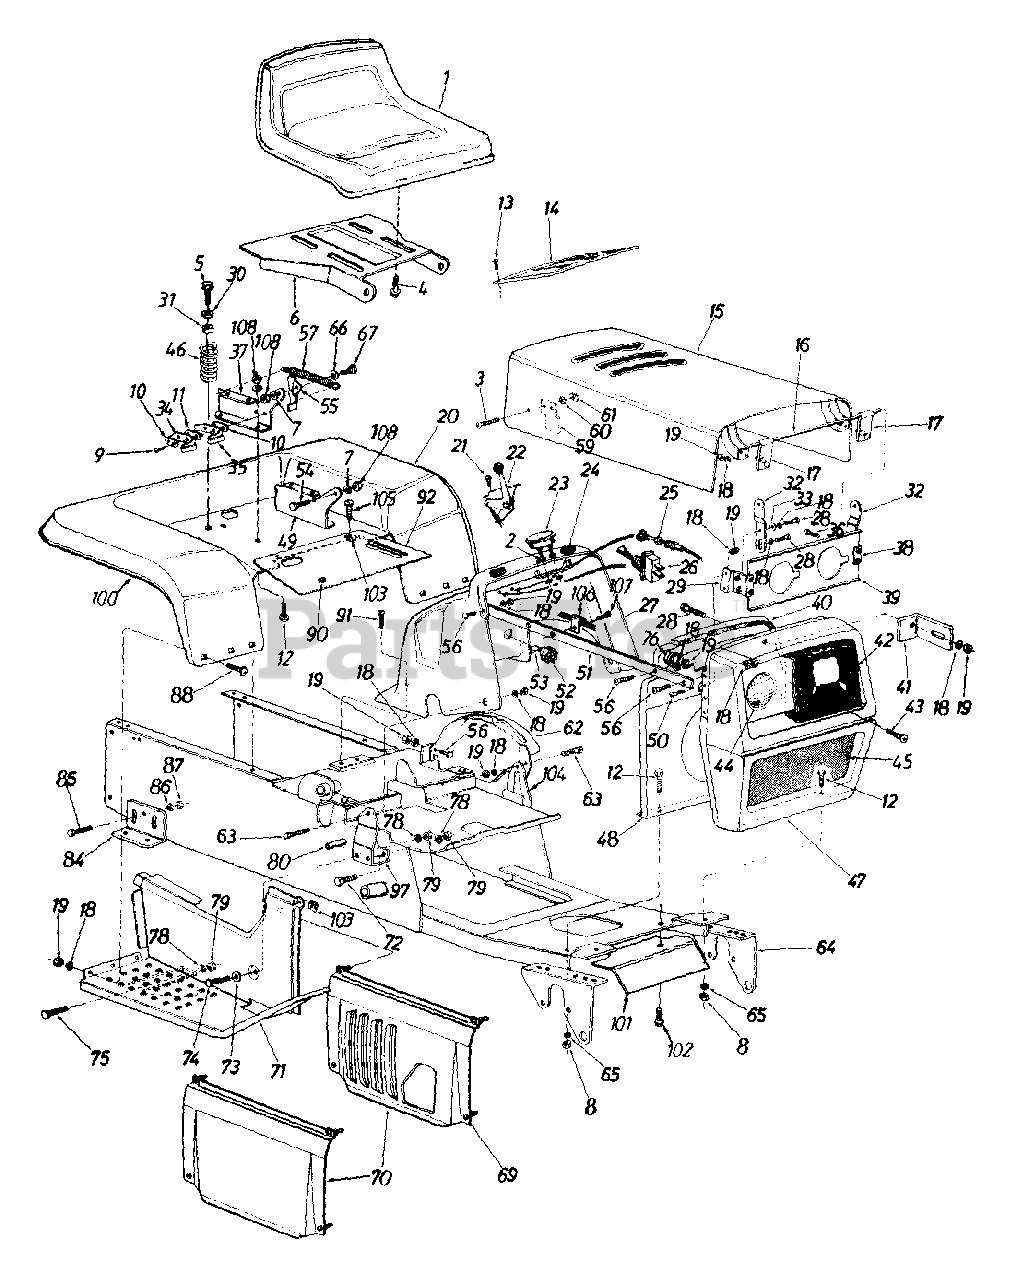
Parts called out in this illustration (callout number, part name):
1	Seat Ass'y.
2	L-Wash. .190" I.D.
3	Truss Hd. Mach. Scr. #10-24 x .38" Lg.
4	Hex Wash. Hd. Self-Tap Scr. 3/8-16 x .62" Lg. (Gr. 5)
5	Hex Wash. Hd. Tap Scr. 5/16-18 x .75" Lg.
7	L-Wash. 5/16" I.D.
8	Hex Nut 5/16-18 Thd.
9	Hex Wash. Hd. AB-Tap Scr. #8 x .5" Lg.
10	Insulator Plate
11	Insulator Boss Plate
12	Hex Bolt 5/16-18 x .75" Lg.
13	Self-Tap Oval Hd. Scr. 1/2" Lg.
14	Dash Panel Cover
17	Hood Hinge Ass'y.
18	L-Wash. 1/4" I.D.
19	Hex Nut 1/4-20 Thd.
22	Throttle Control
23	Ammeter
24	Rubber Bumper
25	Choke Control
26	Light Switch
27	Dash Panel
28	Hex Bolt 1/4-20 x .62" Lg."
29	Hood Support Brkt. Ass'y. - R.H.
30	Fl-Wash. .344" I.D. x .875"
31	Bushing
34	Safety Switch (Seat)
35	Safety Switch (Seat)
36	Hex Bolt 1/4-20 x .38" Lg.
37	Seat Pivot Support Brkt. - R.H.
38	Hood Support Brkt. Ass'y. - L.H.
41	Heat Shield Brkt.
42	Head Lamp Bezel
43	Truss Mach. Scr. #10-24 x .50" Lg.
44	Head Lamp
45	Grille Screen
46	Compression Spring 4.5" Lg.
50	Truss Mach. Scr. 1/4-20 x .75" Lg.
53	Ignition Key
54	Shld. Bolt .437" Dia. x .162"
55	Seat Lift Bracket
56	Hex Bolt 1/4-20 x .75" Lg.
57	Extension Spring 5.31" Lg.
59	Hood Spring
60	L-Wash. #10
61	Hex Nut #10-24 Thd.
62	Speed Control Guide
63	Truss Mach. Scr. 1/4-20 x .75" Lg.
66	Spr. Wash. .445" I.D. x .75"
67	Shld. Bolt .437" Dia. x .268"
69	Truss Mach. Scr. #10-24 x .5" Lg.
73	Fl-Wash. .385" I.D. x .62" O.D.
74	Hex Bolt
75	Hex Bolt 3/8-16 x 1.00" Lg. Grade 5
76	Snap Bushing
78	L-Wash. 3/8" I.D.
79	Hex Nut 3/8-16 Thd.
80	Spacer .375" 1.13. x .62" O.D. x 2.00" Lg.
84	Transaxle Support Brkt.
85	Rd. Hd. Rib Neck Scr. 3/8-24
86	L-Wash. 3/8" I.D.
87	Hex Nut 3/8-24 Thd. (Gr. 5)
88	Carr. Bolt 1/4-20 x .50" Lg.
90	Snap Bushing
91	Hex Wash. Hd. Tap Scr. 1/4-20 x .5" Lg.
103	Speed Nut #10-24 Thd.
104	Dash Panel Mtg. Brkt. - L.H.
105	Truss Mach. Scr. #10-24 x .5" Lg.
106	Clamp
107	Self-Tap Scr. 5/16 x .5" Lg.
108	Hex Nut 5/16-18 Thd. (Gr. 5)
